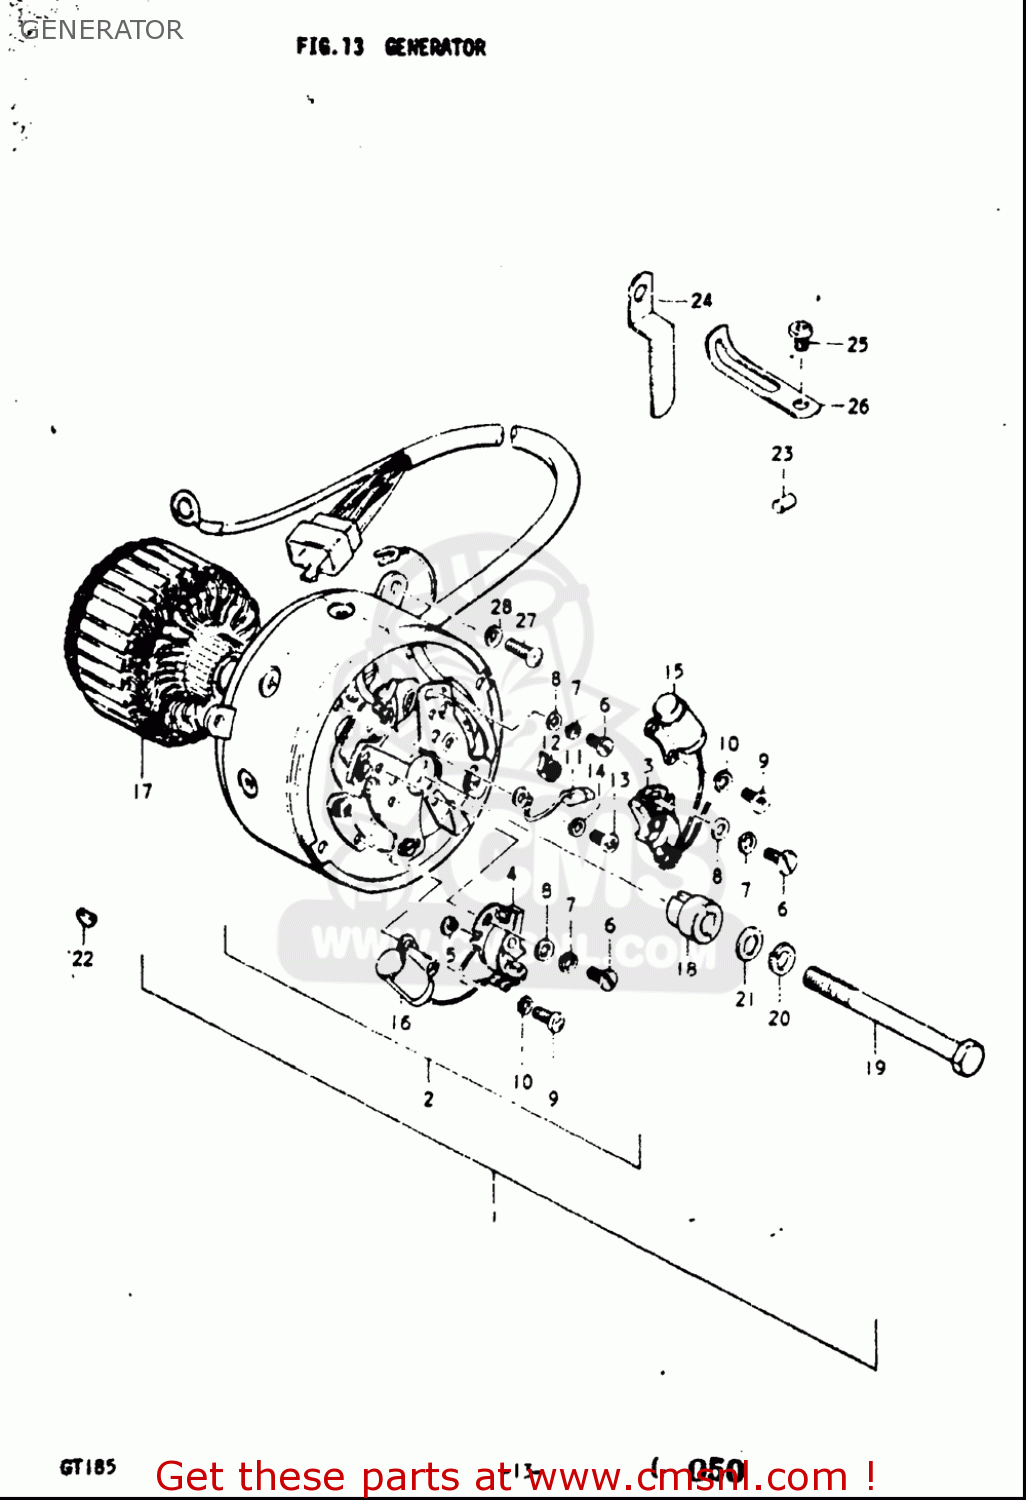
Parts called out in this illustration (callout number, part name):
3	POINT ASSY,CONTACT RH
4	POINT ASSY,CONTACT LH
5	ADJUSTER,CONTACT POINT
6	SCREW(4X10)
7	WASHER,LOCK
8	WASHER
9	SCREW
10	WASHER,LOCK
11	BRUSH
12	SPRING,CARBON BRUSH
13	SCREW 4X6
14	WASHER,LOCK
16	CONDENSER
18	CAM
20	WASHER,LOCK
21	WASHER
22	KEY
23	PIN
25	SCREW
26	CLAMP(L:120 T:1.0)
27	SCREW
28	WASHER,LOCK
